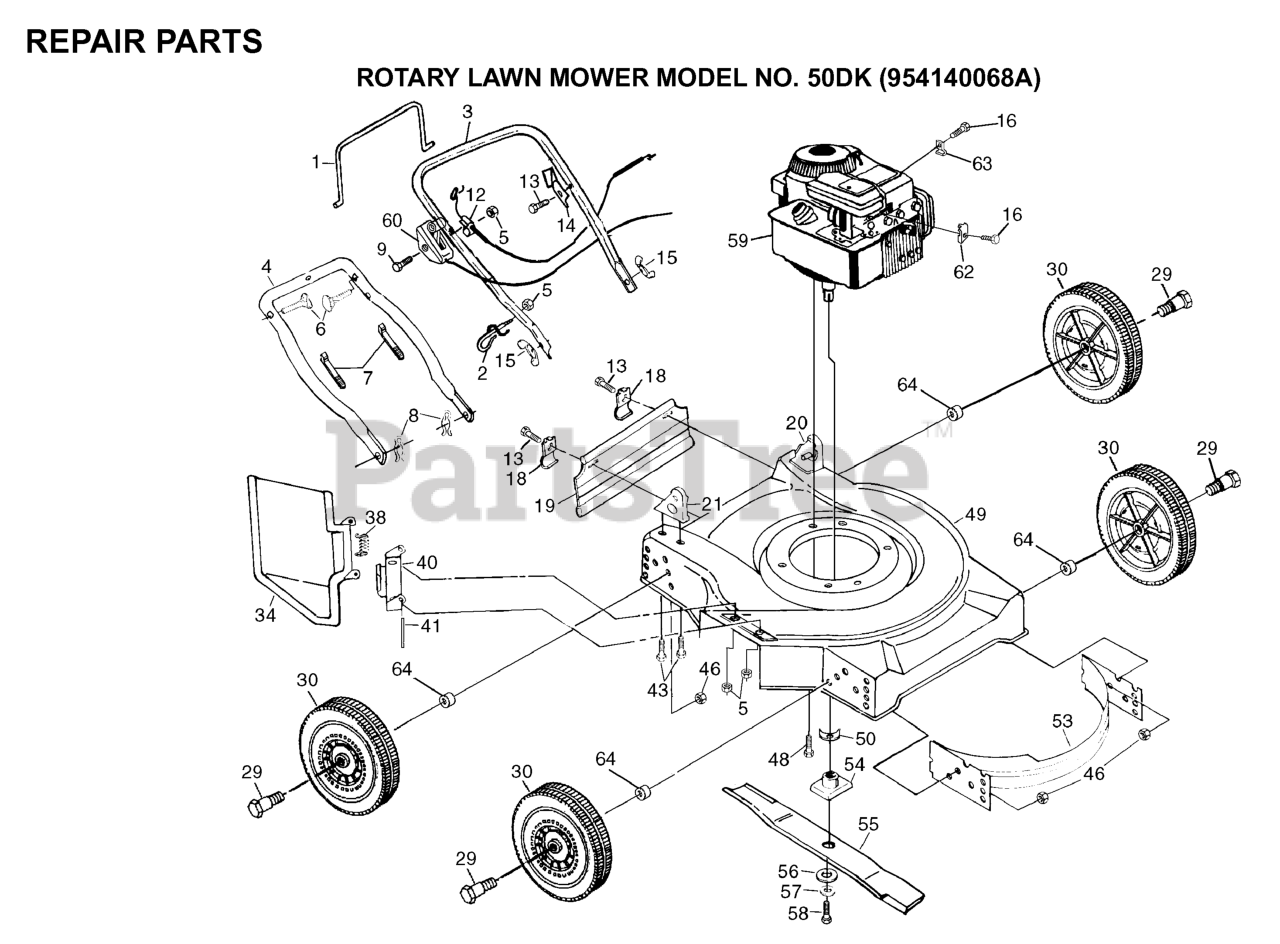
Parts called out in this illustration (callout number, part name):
1	CONTROL BAR
2	ROPE GUIDE
3	UPPER HANDLE
4	HANDLE, LOWER
5	NUT
6	HANDLE BOLT
7	TIE GUIDE
8	HAIRPIN COTTER
9	SCREW.PAN.HEAD
12	CABLE.MZR.51.RT.SP./PU.
13	TAPPING SCREW
14	BRACKET UPSTOP
15	NUT WING PM
16	SCREW.HEX.HEAD.WASHER.10-16
18	BRACKET DEFL PM
19	REAR SKIRT
20	HDLE BRKT ASSY LH
21	HDLE BRKT ASSY RH
30	DNO WHEEL.7.5X1.5.PR.SP.GY
38	SPRING TENSION
43	SCREW.5/16-18X3/4
46	LOCKNUT PM
48	BOLT 3/8-16X1-1/8
50	WASHER.ENGINE.BZP
53	BAFFLE
54	BLADE ADAPTOR
55	BLADE.20.MULCH.(50DK,6020MD)
56	WASHER,HARDEN
57	LOCKWASHER
58	SCREW, HEX HD 3/8-24 X 1-3/8
60	THROTTLE CONTROL
63	GUIDE CLIP PM
64	SPACER.WHEEL.390.X1.0X.380.RTA
